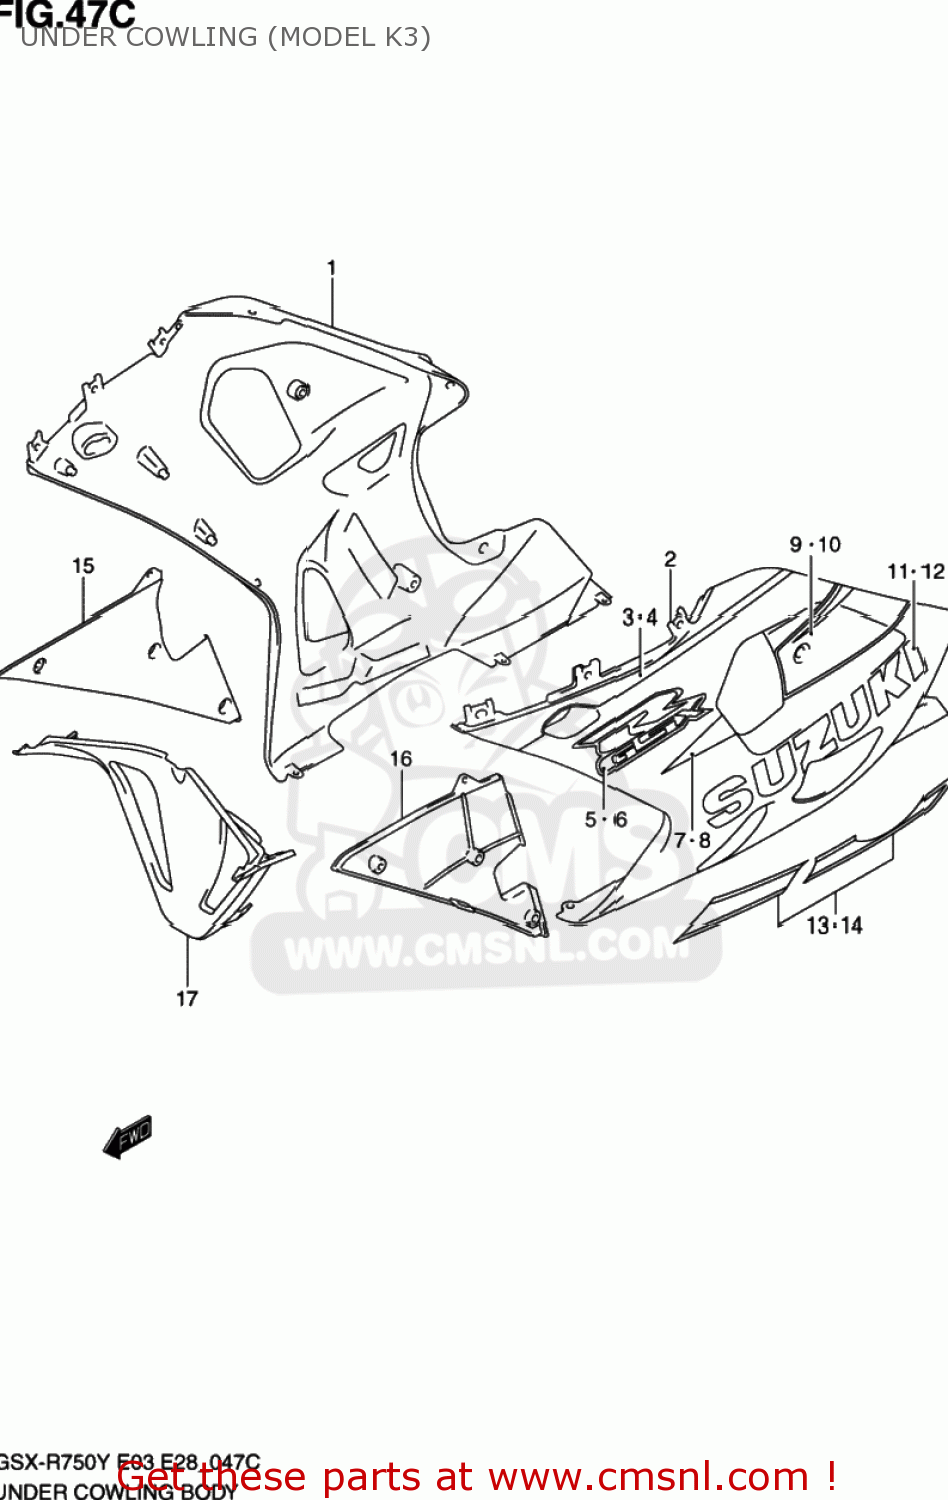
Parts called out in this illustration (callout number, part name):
1	COWLING ASSY,UNDER,R
2	COWLING ASSY,UNDER,L
3	TAPE SET,UPR,R
4	TAPE SET,UPR,L
5	EMBLEM,GSXR,R
6	EMBLEM,GSXR,L
7	TAPE,CTR FR,R
8	TAPE,CTR FR,L
9	TAPE,CTR,R
10	TAPE,CTR,L
11	EMBLEM,SUZUKI,R
12	EMBLEM,SUZUKI,L
13	TAPE SET,LWR,R
14	TAPE SET,LWR,L
15	COWLING,UNDER INNER,R
16	COWLING,UNDER INNER,L
17	COWLING,UNDER CTR
